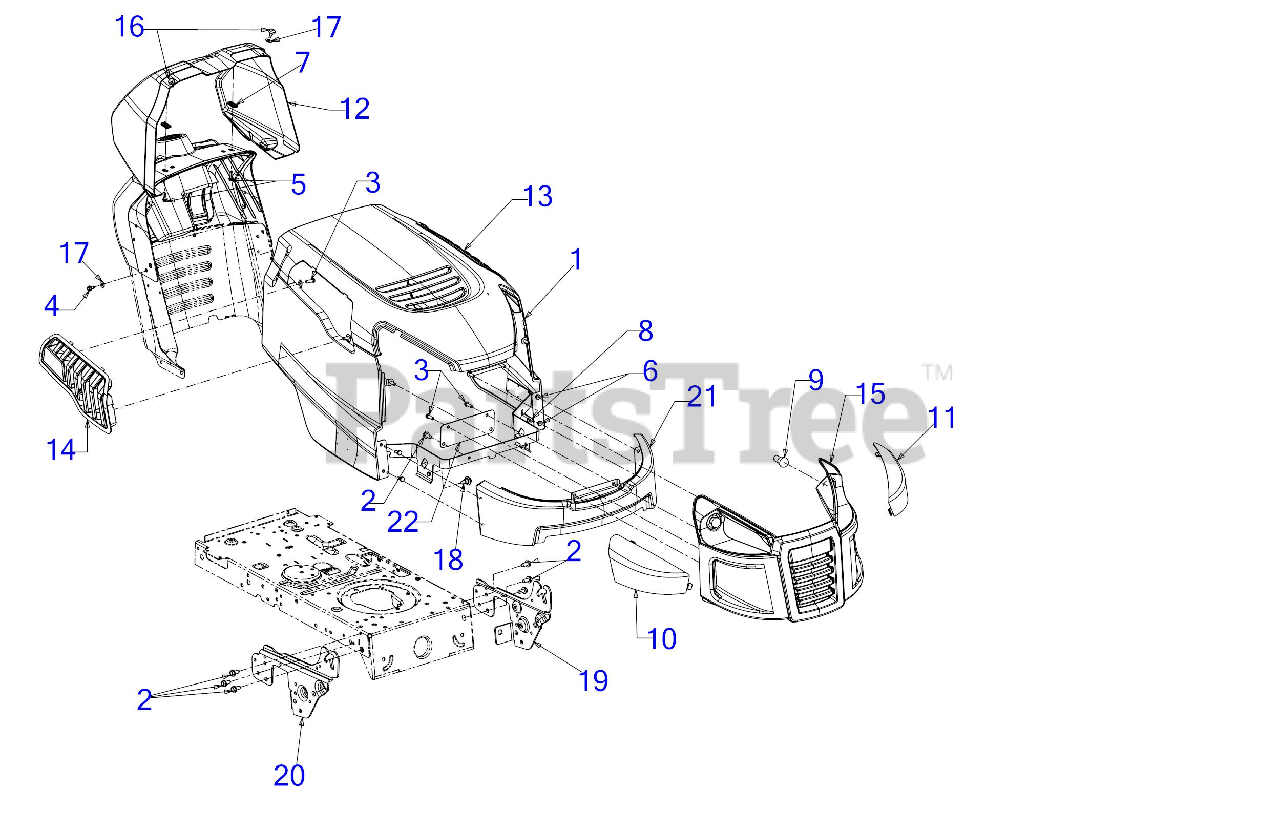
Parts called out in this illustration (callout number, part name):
2	SCREW 5/16-18 x .750
3	SCREW 1/4 x .750
4	SCREW 1/4-20 X.500
5	SCREW 1/4-20 x .750
6	SCREW 1/4-20 x .620 GR5
7	SPEED NUT
8	FLANGE LOCK NUT
9	MINIATUURE BULB 12V
10	LENS (RH)
11	LENS (LH)
12	DASH COLLER
13	HOOD SCOOP (LH)
14	HOOD SCOOP (RH)
15	GRILLE(S STYLE) W/O LABEL
16	BUMPER, .62 DIA x .3
17	FLAT WASHER
18	SHOULDER SCREW .43X.29X5/16-18 TT
22	LOWER GRILLE BRACKET
